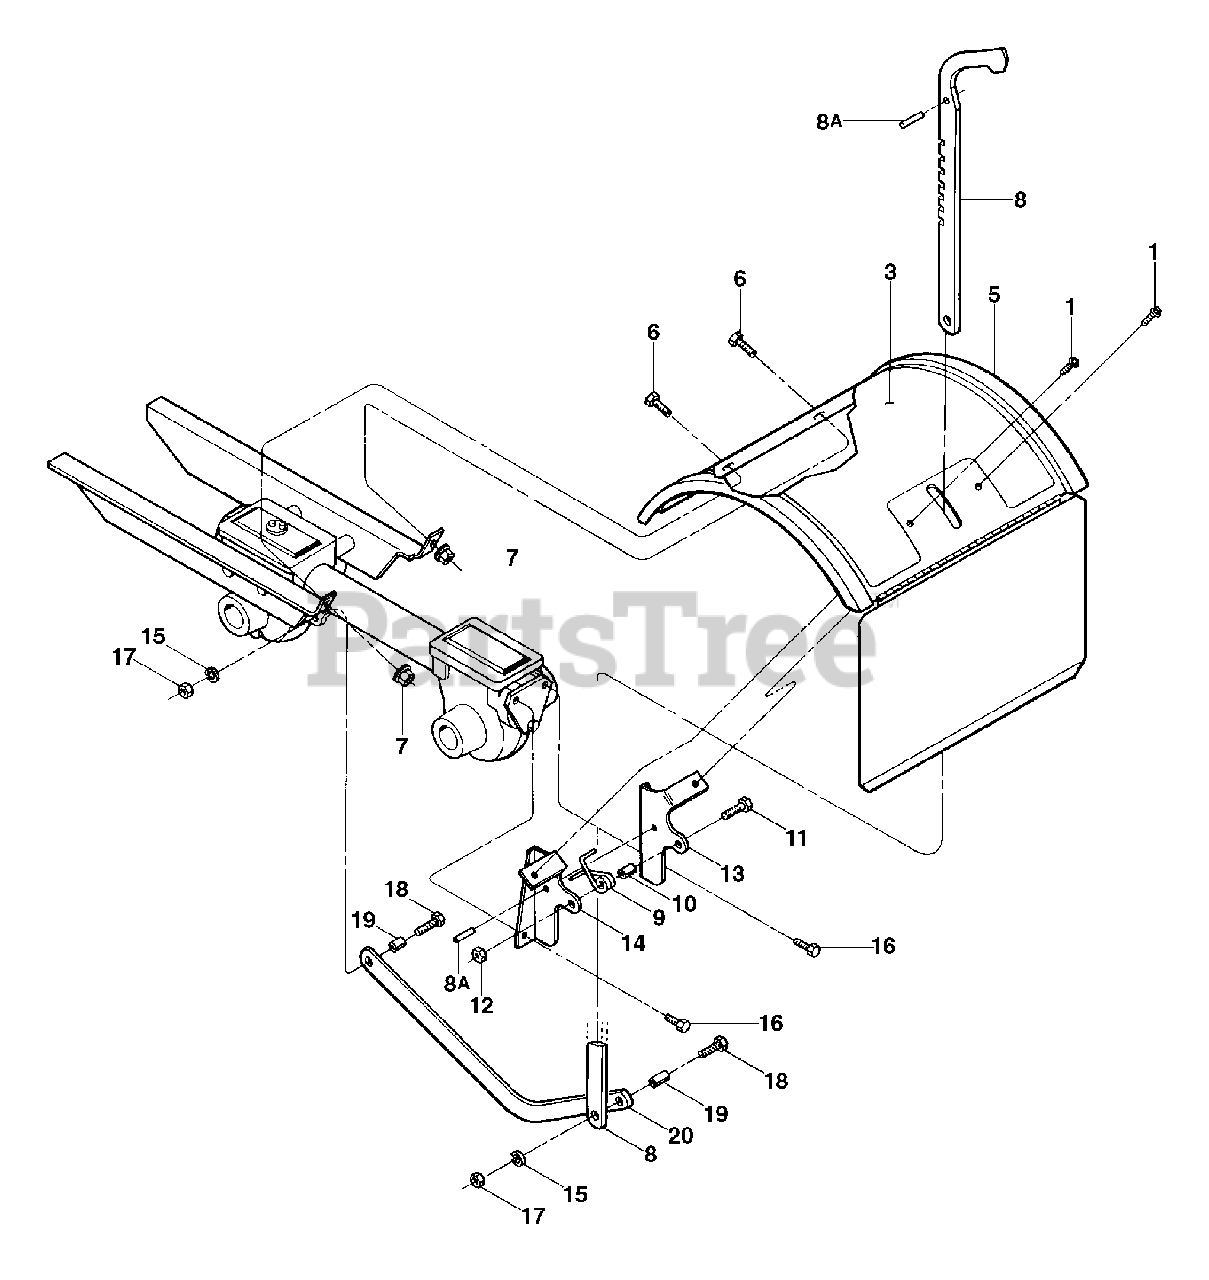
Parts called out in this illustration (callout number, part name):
1	Flange Screw, Self-Tapping, 1/4-20 x 1/2
3	Decal-Hood
5	Tine Hood
6	Hex Screw, 5/16-18 x 1/2
7	Nut, Flange Lock, 5/16-18
8	Depth Regulator Lever
8A	Spirol Pin
9	Spring-Depth Regulator
10	Spacer
11	Hex Screw, 1/4-20 x 1
12	Locknut, 1/4-20
13	Bracket-Hood, Right Hand
14	Bracket-Hood, Left Hand
15	Lockwasher, 5/16
16	Flange Screw, 5/16-18 x 1
17	Hex Nut, 5/16-18
18	Hex Screw, 5/16-18 x 1-1/4
19	Bushing
20	Drag Bar
